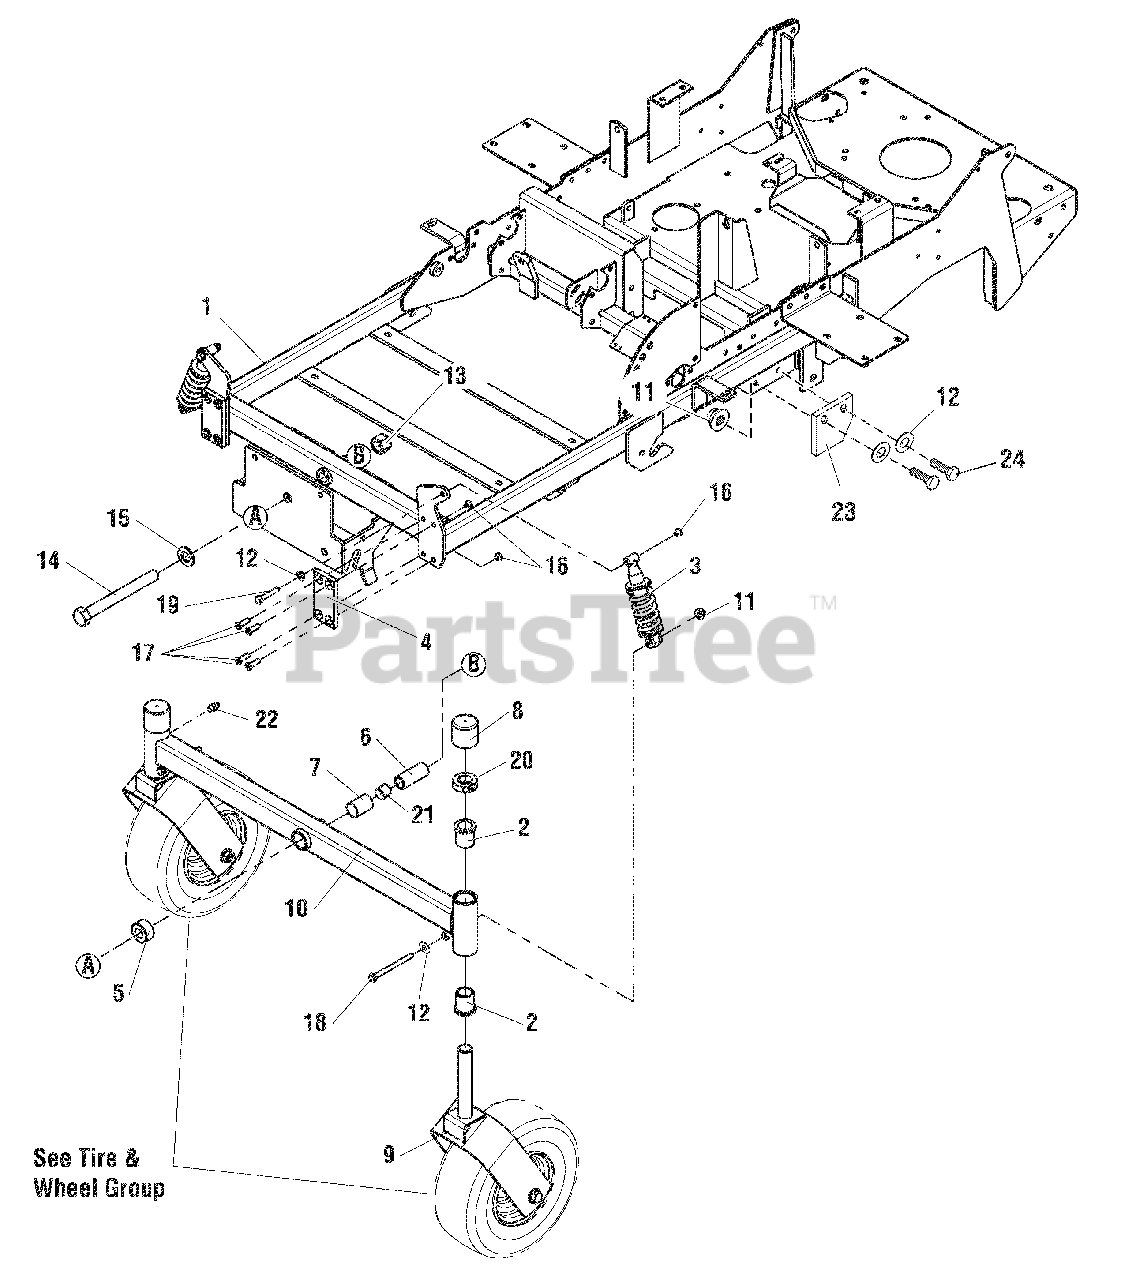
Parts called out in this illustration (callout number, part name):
1	WELD, MAIN FRAME, SMI
2	BUSHING, FLANGE
3	SHOCK
4	FRICTION PLATE
5	SPACER, .76X 1.50 X .79, CZ
6	SPACER, .75 x 1.00 x 2.38
7	PIVOT BEARING, 1.00" X 1.125" OD X 1.50"
8	CAP, VINYL 1.687 X 1-1/2
9	WELD, CASTER YOKE - RED
10	WELD, PIVOTING FRONT END - ORG
11	NUT, 5/16-18 HEX NYLOCK FLANGE NUT
12	WASHER, 5/16" SAE
13	NUT, Hex, Nylon Lock, 3/4-16
14	3/4-16 X 7" GD 8 BOLT TZ
15	WASHER, 3/4" SAE
16	NUT, Hex, Nylon Locking, 5/16-18
17	SCREW, FLAT HEAD SOCKET, 5/16-18 X 3/4
18	BOLT, 5/16-18 X 3-3/4 GD5
19	BOLT, 5/16-18 X 1-3/4" GD5 YZ
20	COLLAR, 1" Split
21	PIVOT BEARING, 1.00" X 1.125" OD X .50"
22	GREASE FITTING, 1/4-28 Straight
23	PLATE, DECK STOP - SNAPPER RED
24	BOLT, 5/16-18 X 3/4 GD5
